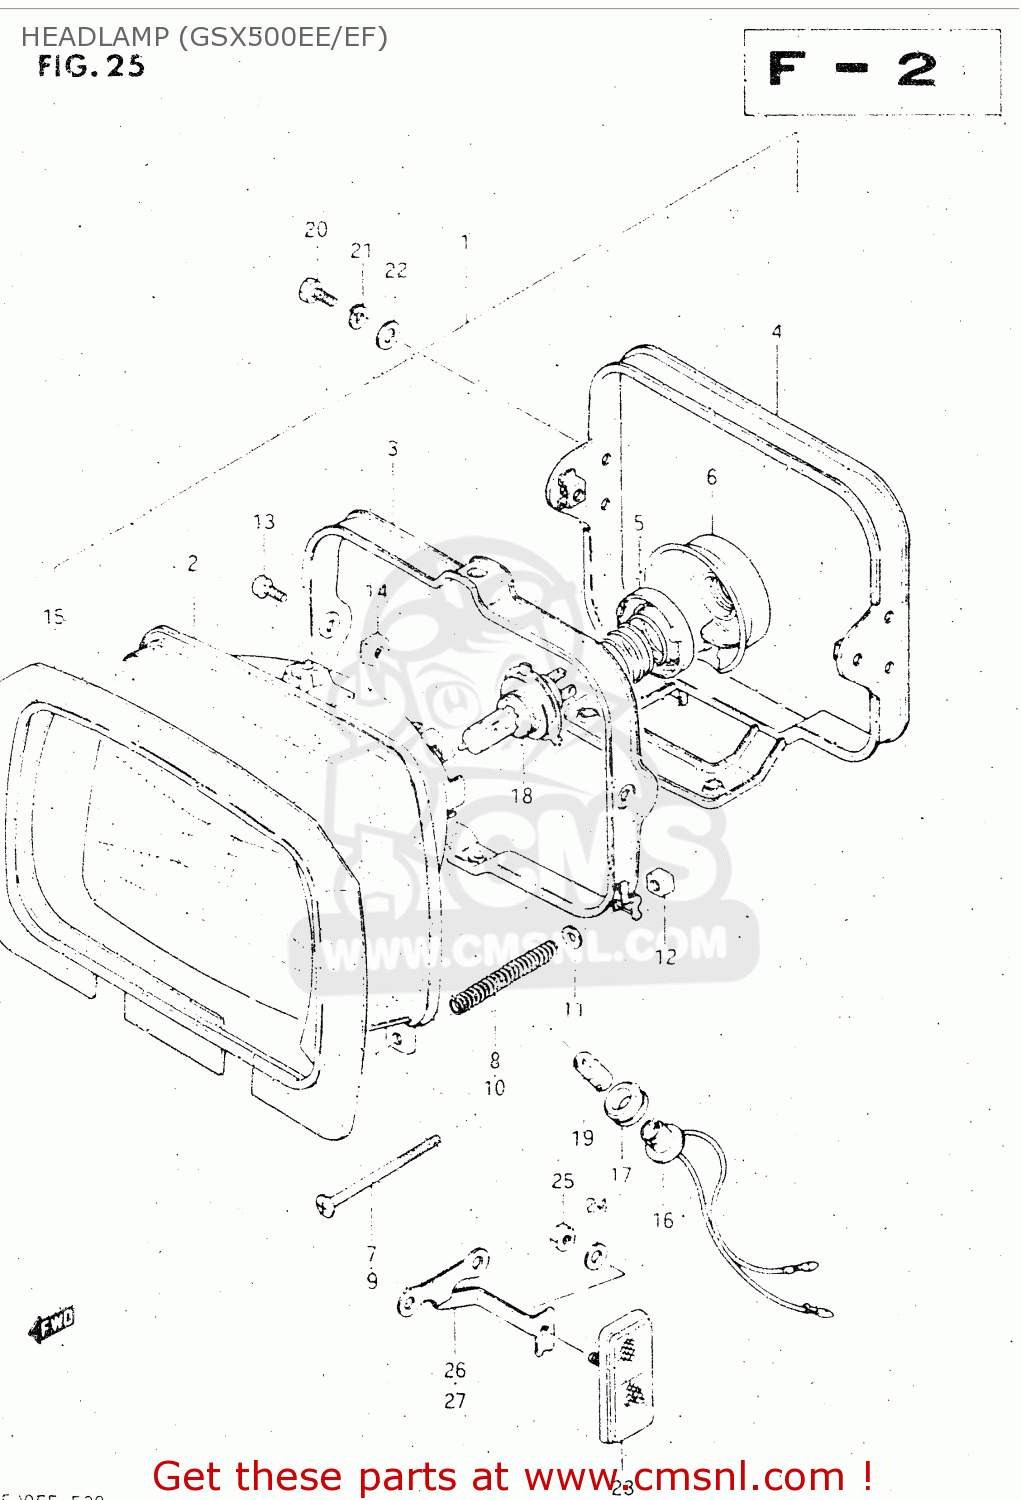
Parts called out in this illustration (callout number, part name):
1	HEADLAMP ASSY
2	UNIT
3	RING,MOUNTING
4	HOUSING
5	HOLDER
6	COVER,HEADLAMP SOCKET
7	SCREW,HEADLAMP ADJUST
8	SPRING
9	SCREW,HEADLAMP ADJUST
10	SPRING,HEADLAMP ADJUST
11	WASHER
12	NUT
13	SCREW
14	NUT
15	SHADE
16	SOCKET
17	JOINT,RUBBER
18	BULB(12V60/55W,H4)
19	BULB(12V4W)
20	BOLT
21	WASHER,LOCK
22	WASHER, LOWER
23	REFLEX REFLECTOR, FRONT SIDE
24	WASHER,5MM
25	NUT ,5MM
26	BRACKET, RH
27	BRACKET, LH
